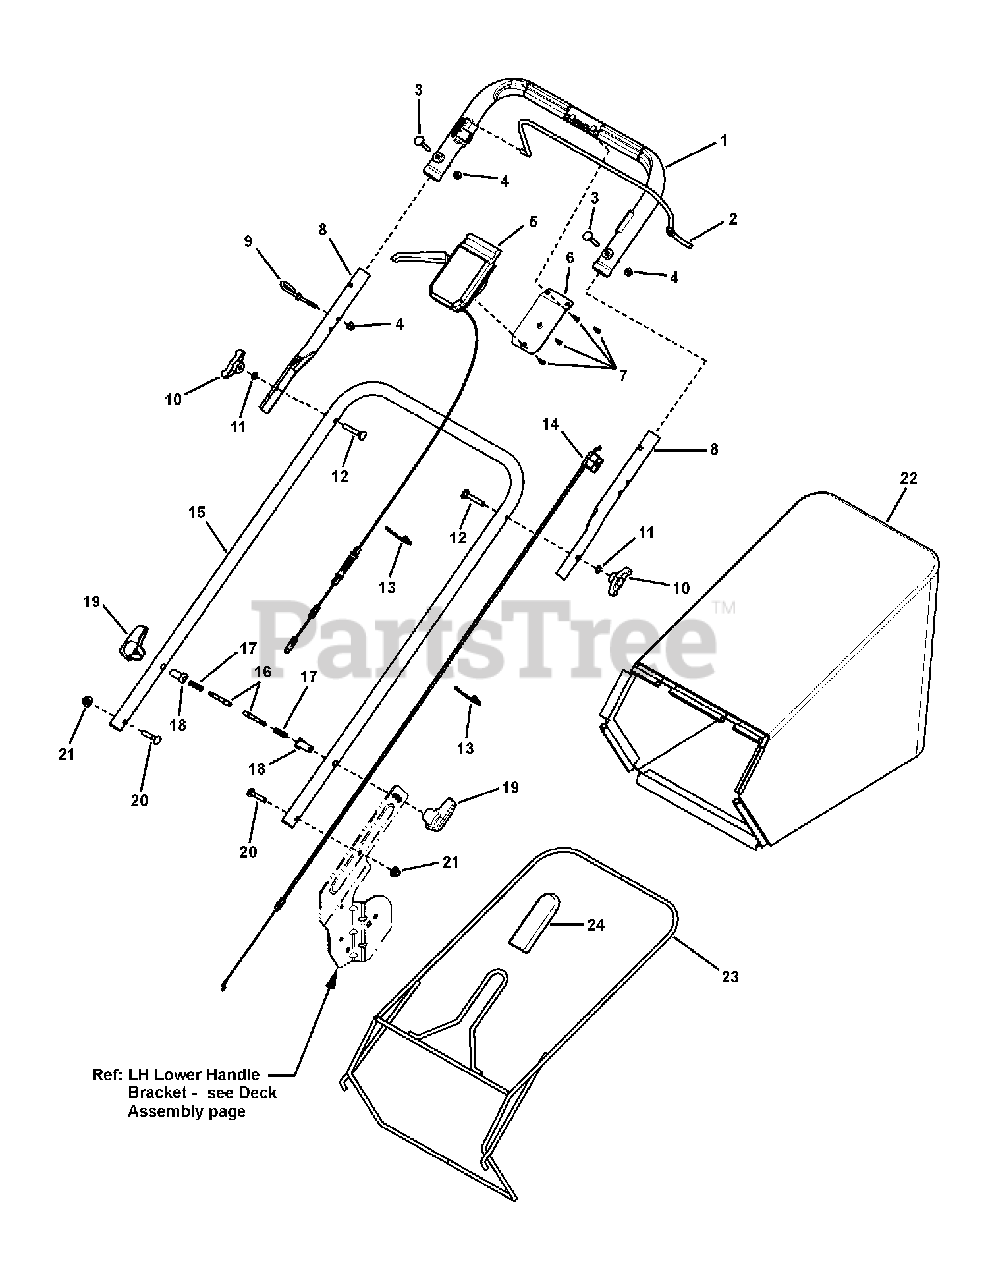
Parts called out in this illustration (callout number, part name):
1	HANDLE, Plastic Upper, WBM
2	BAIL, Plastic Handle, WBM
3	BOLT, 1/4-20 x 1-3/4 Round Head Square Neck, GR 2
4	NUT, 1/4-20, Hex Flange Nyloc, YZ
5	ASSEMBLY, Control Head, 22 WBM, VS, HW (incl. cable & lever)
6	PLATE, Control Panel- Plastic Handle
7	SCREW, #8-16 Torxplus Recessed Pan Head, Twin Helix
8	HANDLE, Connecting 21/22 WBM
9	ROPE GUIDE (1/4-20 thread)
10	KNOB, 5/16-18 Wing (Black)
11	WASHER, 5/16" Internal Tooth Lock
12	BOLT, 5/16-18 x 2 Curved Head Square Neck, GR 2
13	WIRE TIE,11 Inch Standard Black Nylon
14	CABLE, Bail, 22 WBM
15	HANDLE, Lower, 22 WBM, Hi-Wheel
16	PIN, Handle Adjust
17	SPRING, Compression
18	BUSHING, Handle Pin
19	KNOB, Quick Release
20	BOLT, 5/16-18 x 1-1/2" Round Head Short Square Neck, GR 5
21	NUT, 5/16-18 Large Head Center Lock, Black
22	GRASS BAG, 22" Rear Discharge
23	BAG FRAME, 22" WBM (Weldment)
24	GRIP, Rectangular (Black)
